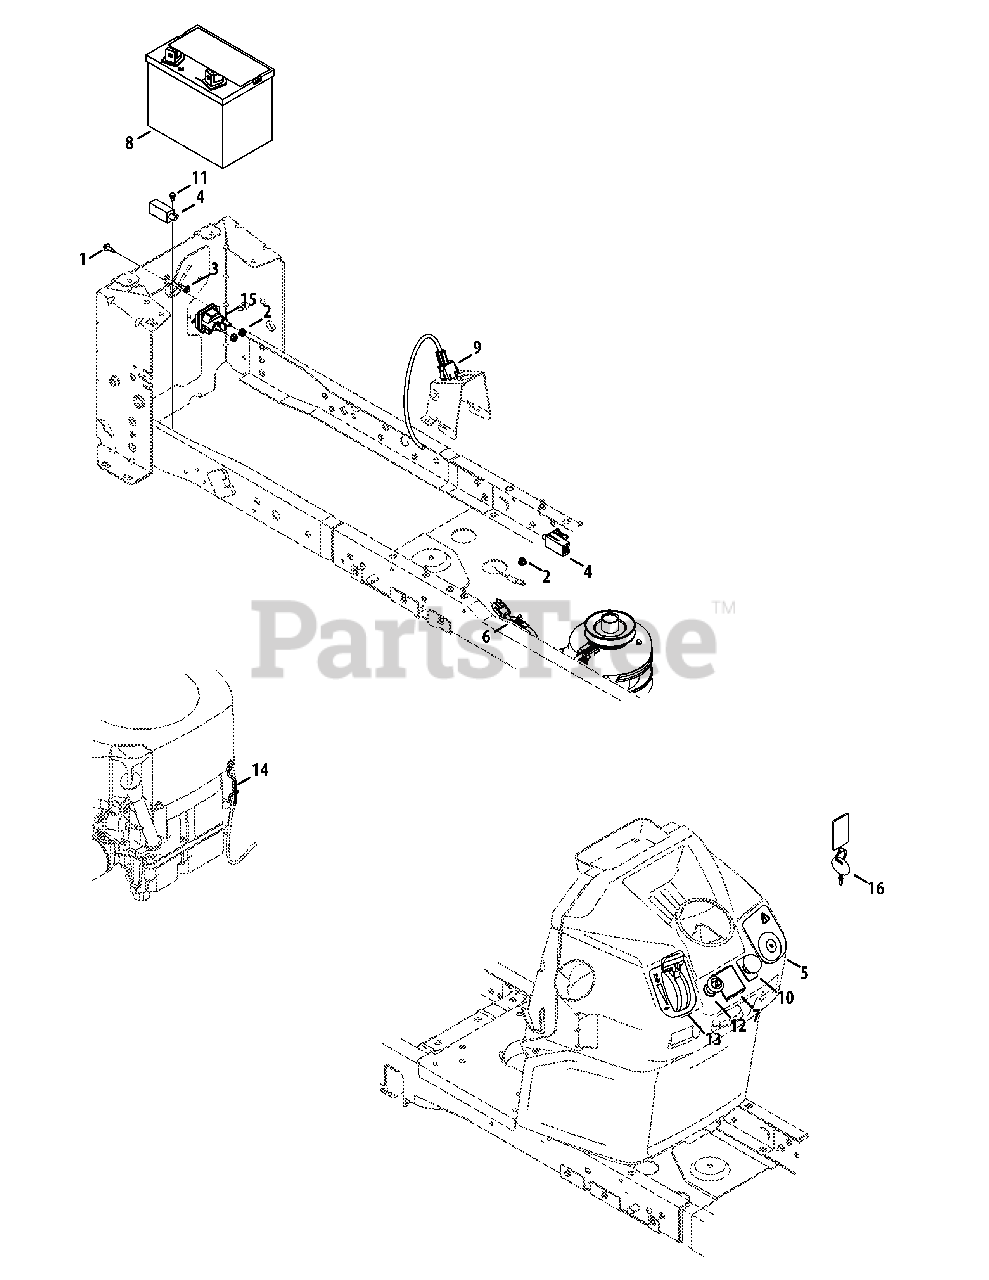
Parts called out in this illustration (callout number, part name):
1	Screw, M6-1 x .625
2	Nut, Jam Lock, 1/4-20, Nylon
3	Self-tapping Screw, 1/4-20 x .625
4	Switch, Interlock
5	Key Switch
6	Jumper Harness
7	Hour Meter
9	Dash Harness
10	PTO Switch
11	Shoulder Screw, #10-32 x .500
12	Choke Plug
13	Throt/Choke Cable, 43.5"
14	Cable Guide Rod
15	Solenoid
16	Key, Assembly
